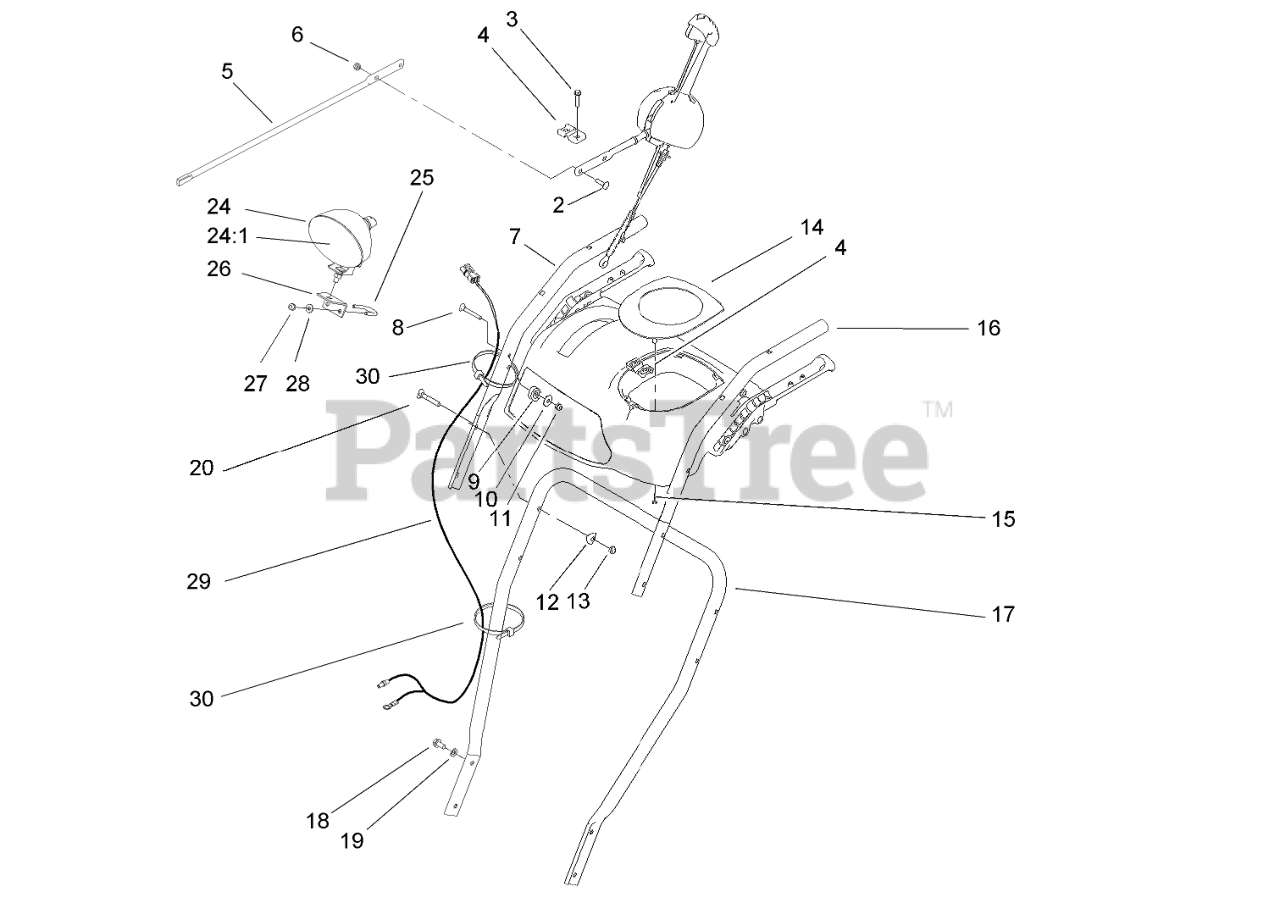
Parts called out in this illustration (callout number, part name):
2	SCREW-CARR
3	SCREW-PLASTITE
4	SUPPORT-ROD
5	ROD-CHUTE, FRONT
6	NUT-LOCK, NI
7	HANDLE-UPPER, RH
8	SCREW
9	CLAMP-CABLE
10	WASHER-PLAIN
11	NUT-LOCK, NI
12	WASHER
13	NUT-LOCK, NI
14	COVER-PANEL, CONTROL
15	SCREW-PPH
16	HANDLE-UPPER, LH
17	HANDLE-LOWER
18	SCREW-HWHTF
19	WASHER-BELLEVILLE
20	SCREW-HANDLE
24	HEADLAMP ASM
24:1	LAMP-12 VOLT
25	CLAMP
26	BRACKET-LIGHT
27	NUT-LOCK, NI
28	WASHER-FLAT
29	HARNESS-WIRE
30	TIE-CABLE
